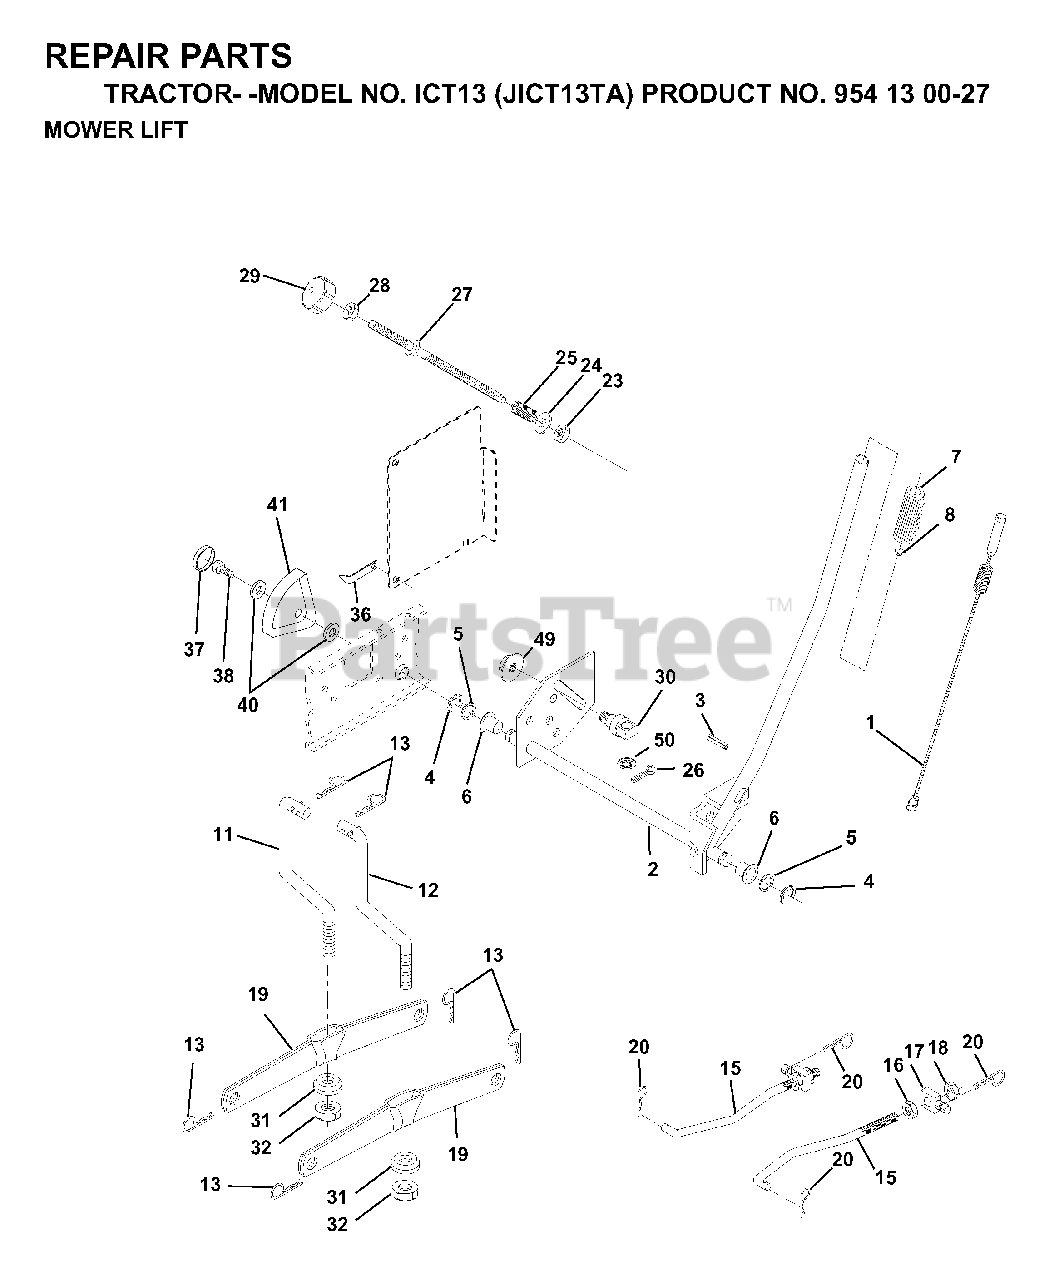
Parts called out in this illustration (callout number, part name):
1	WIRE ASM INNER W/ PLUNGER LT
2	SHAFT ASM R HANDLE
3	PIN GROOVE
4	RETAINING RING LT
6	BEARING.NYLON
7	GRIP HANDLE
11	LINK
12	LINK
13	RETAINER-SPRNG RB
15	FRONT LINK
16	NUT
17	TRUNION
18	NUT LTV
19	ARM.REAR.SUSPENSION
20	SPRING RETAINER
25	SPRING**
26	COTTER PIN
27	ROD ADJ LIFT
28	NUT
29	KNOB INF 3/8-16
31	BEARING PIVOT
32	NUT CROWNLOCK 3/8-24
36	POINTER, HEIGHT INDICATOR
37	PLUG,HOLE
38	SCREW
41	HEIGHT INDICATOR
49	NUT
50	NUT PUSH M
